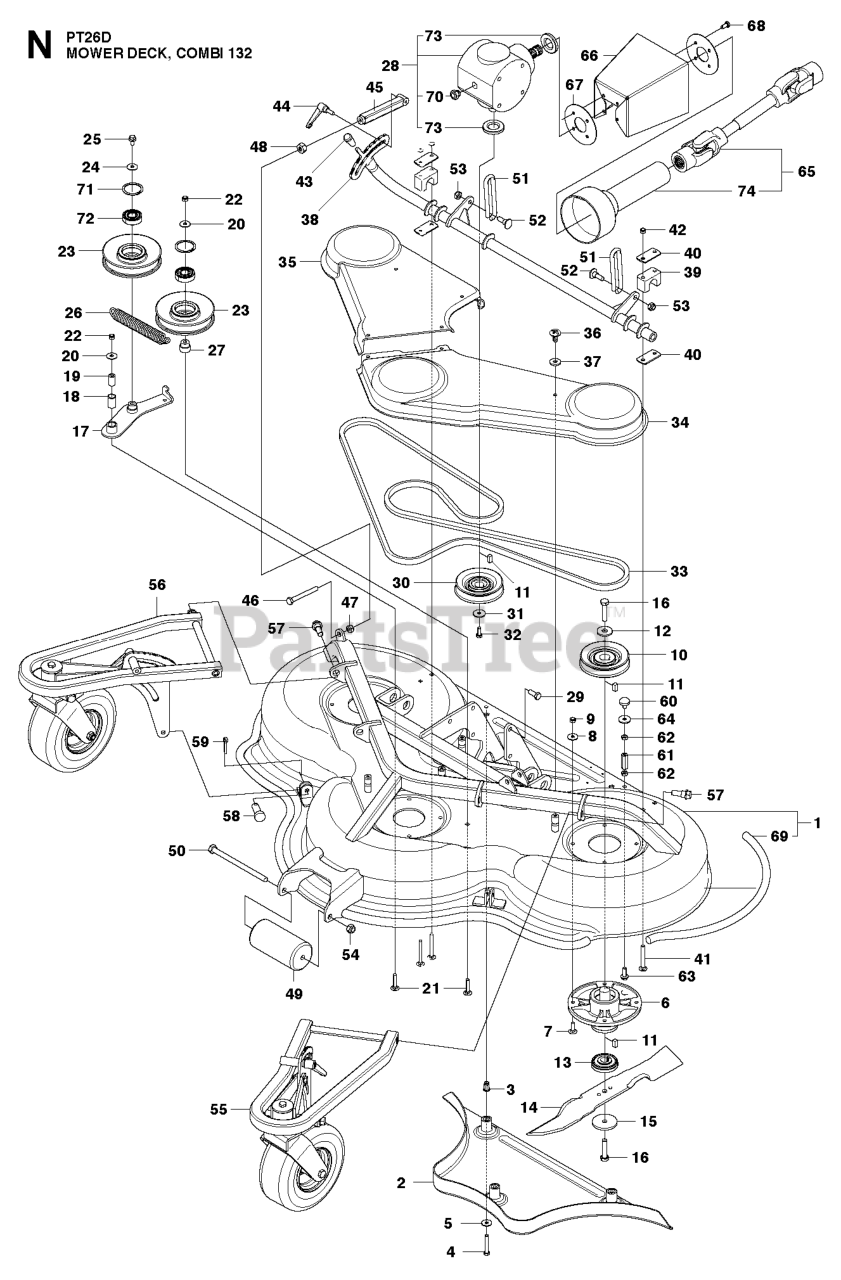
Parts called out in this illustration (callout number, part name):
1	CUTTING DECK ASSY C132
3	BLIND RIVET NUT
5	WASHER BRB 8.4X17
8	WASHER BRB 8.4X17
9	LOCKNUT M8
14	BLADE REAR DISCHARGE/MULCH C13
17	BELT TENSIONER CUTTING DECK
21	Screw Mvbf 8 X 40
22	LOCKNUT M8
25	BOLT FLANGE - M8X16
26	DRAW SPRING L=122
28	BEVEL GEAR
29	Screw M10x25
35	BELT COVER C132 R
42	LOCKNUT M8
44	TURNING KNOB M 8
45	PARALLEL ROD C 132
48	NUT
49	ROLLER
52	SCREW LINK
53	NUT
55	WHEEL SUSPENSION LEFT
56	WHEEL SUSPENSION RIGHT
60	ANTIVIBRATION ELEMENT
62	NUT
71	CIRCLIP SGH 47
72	BALL-BEARING 6204-2RS
